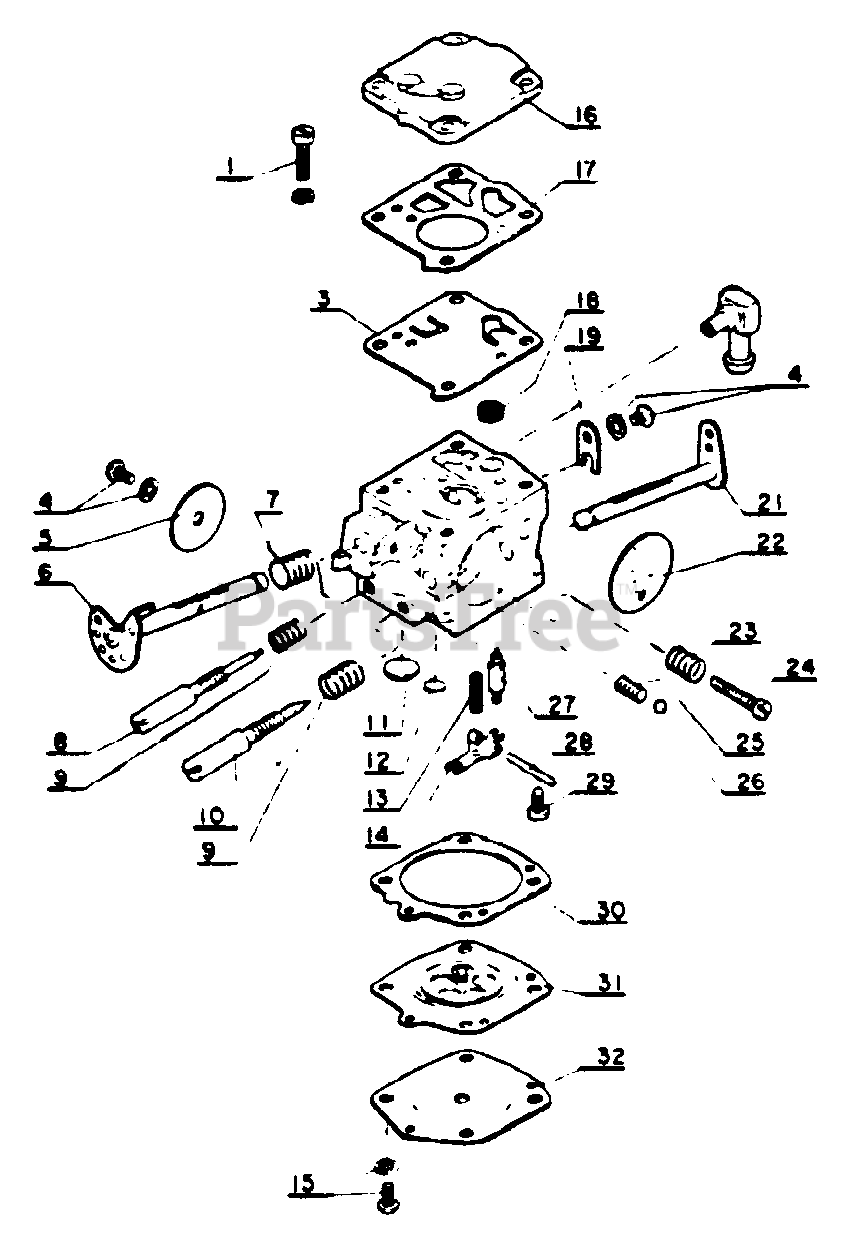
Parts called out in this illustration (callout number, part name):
1	SCREW
3	DIAPHRAGM, PUMP
4	SCREW
5	VALVE, THROTTLE
6	SHAFT, THROTTLE
7	SPRING, RETURN
8	SCREW, IDLE ADJUST
9	SCREW, IDLE ADJUST
10	SCREW, MAIN ADJUST
11	PLUG, WELCH - LARGE
12	PLUG, WELCH - SMALL
13	SPRING, METERING LEVER
14	LEVER, METERING
15	SCREW
16	COVER, PUMP
17	GASKET, PUMP
18	STRAINER
19	RING, RETAINING
20	SCREW, IDLE ADJUST
21	SHAFT, CHOKE
22	VALVE, CHOKE
23	SPRING, IDLE ADJUST
24	SCREW, IDLE ADJUST
25	SPRING, CHOKE
26	BALL, CHOKE
27	VALVE, INLET NEEDLE
28	PIN, METERING LEVER
29	SCREW, METERING LEVER PIN
30	GASKET, DIAPHRAGM
31	DIAPHRAGM
32	COVER, DIAPHRAGM
